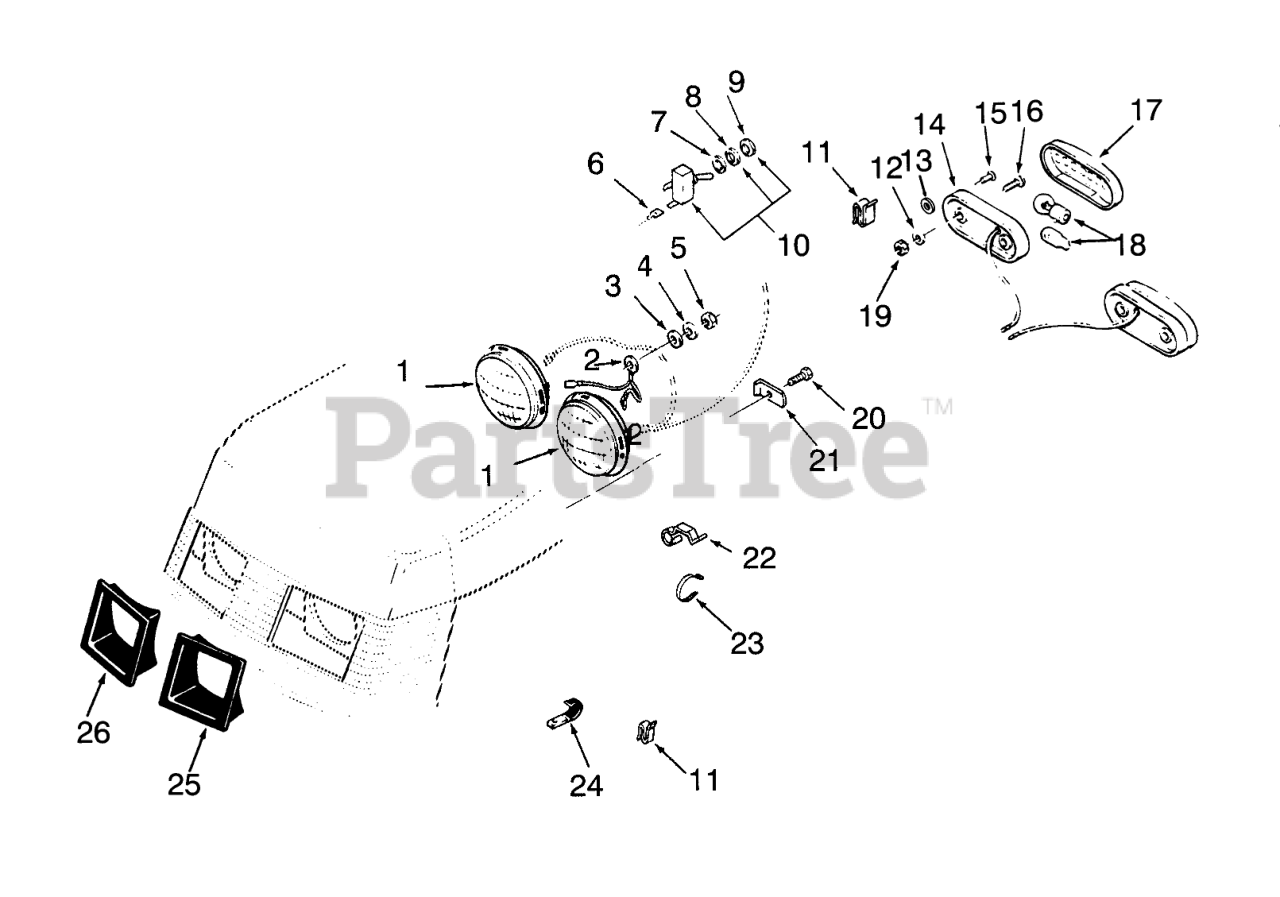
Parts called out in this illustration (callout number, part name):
1	HEADLAMP
2	LIGHT GROUND WIRE
3	WASHER-PLAIN
4	WASHER-LOCK, INTERNAL
5	NUT-LOCK, NI
6	Terminal
7	WASHER
8	TAB-WASHER
10	SWITCH-LIGHTS
11	SPEED CLIP
12	WASHER-FLAT
13	WASHER-LOCK, INT
14	BASE-TAIL LIGHT
15	RIVET-POP
16	Screw
17	LENS-TAIL LIGHT
18	Bulb
19	Nut
20	Bolt
21	LOCK-HEADLIGHT
22	CLIP-WIRE
23	PLASTIC TIE
24	CLIP
25	BEZEL-HEADLIGHT, LH
26	BEZEL-HEADLIGHT, RH
